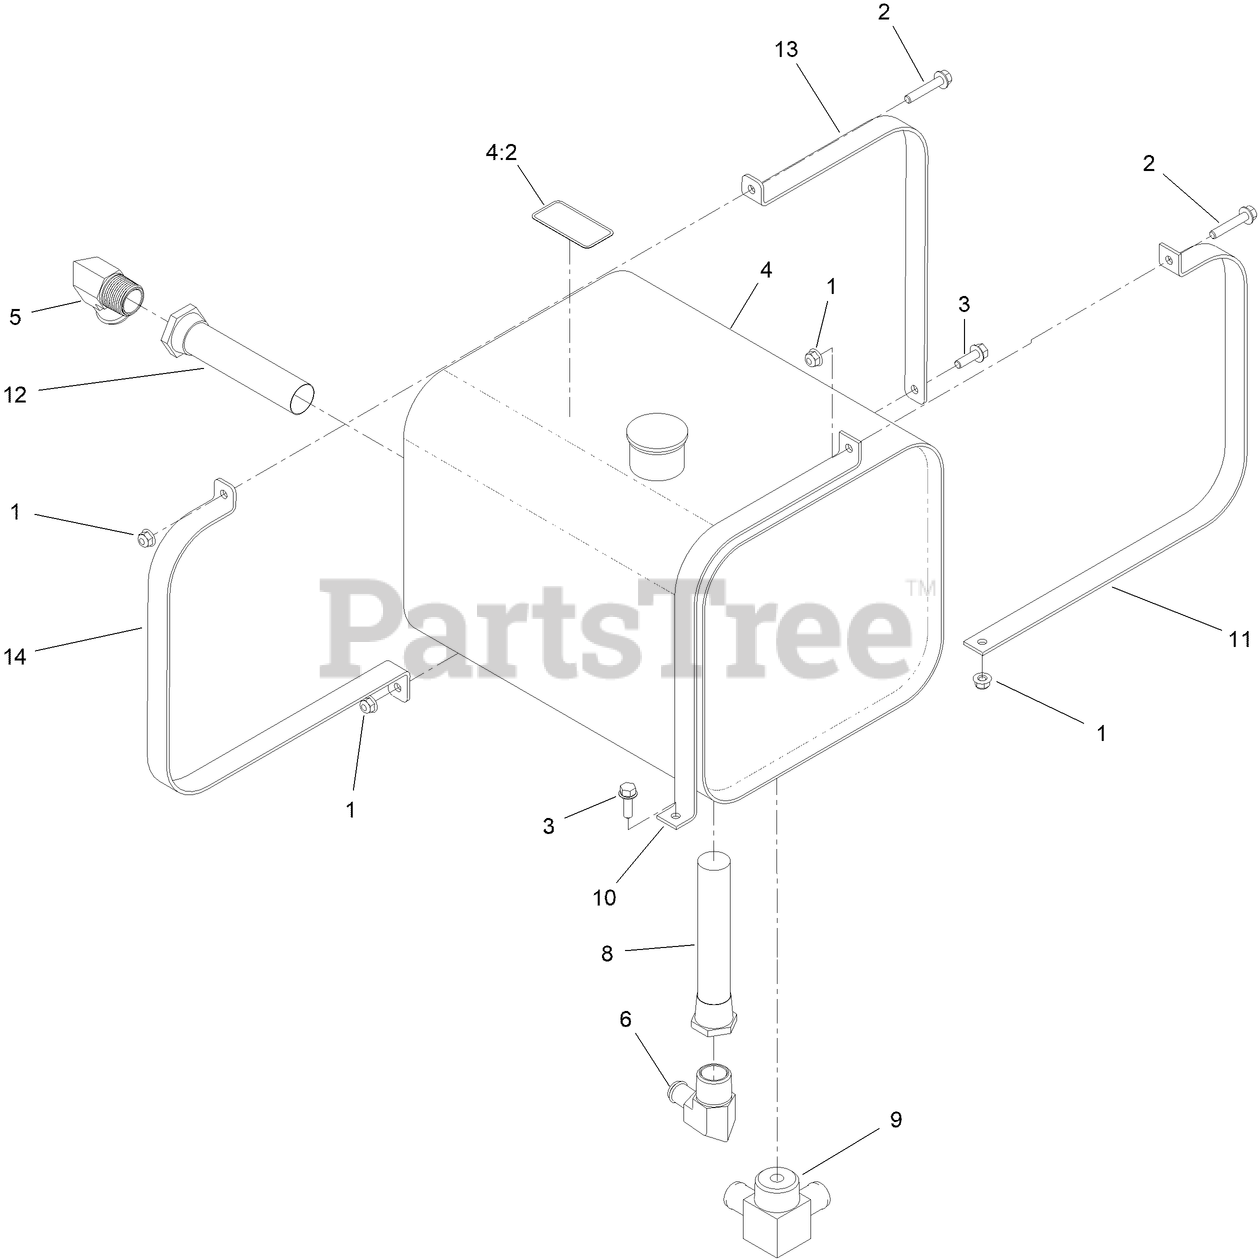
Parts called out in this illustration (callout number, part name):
1	NUT-HF, NI
2	SCREW-HWH
3	SCREW-HHF
4	HYD TANK ASM
4:2	DECAL-HYD FLUID
5	FITTING-ELBOW, 90
6	FITTING-ELBOW, 90
8	FILTER ASM
9	INDUCER-PRESSURE
10	STRAP-TANK
11	STRAP-TANK
12	FILTER ASM
13	STRAP-TANK
14	STRAP-TANK
